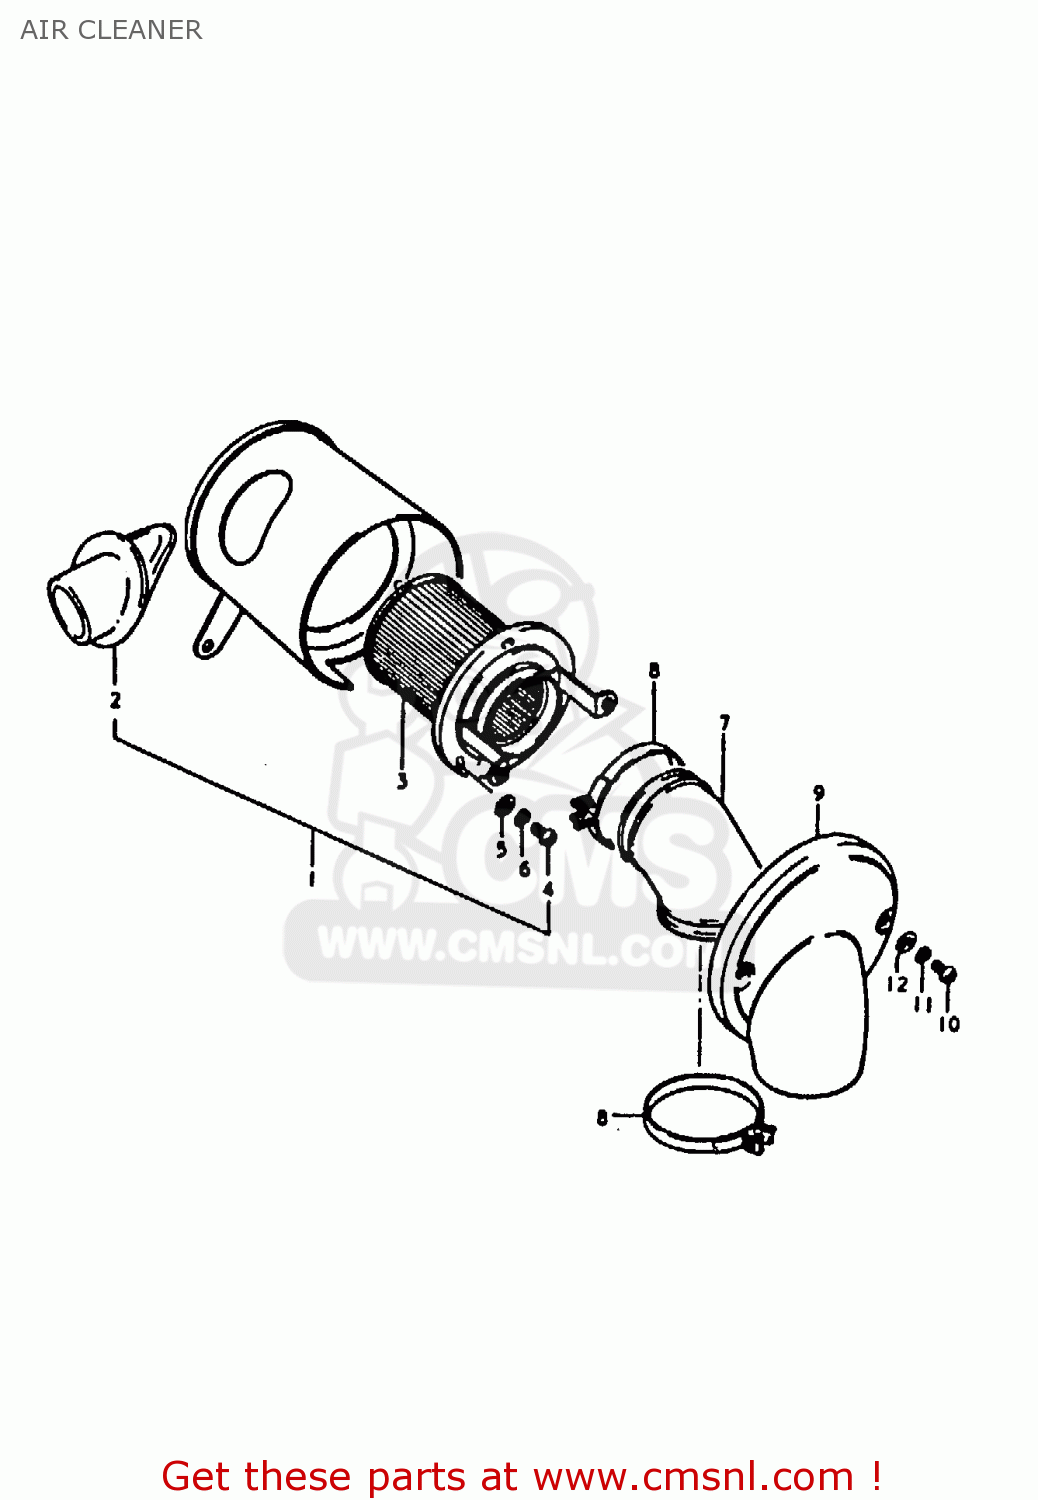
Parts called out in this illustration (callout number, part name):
1	CLEANER ASSEMBLY,AIR
2	PIPE,AIR CLEANER INLET
3	FILTER ASSY
4	SCREW
5	WASHER
6	LOCK WASHER
7	HOSE,CARBURETOR AIR INLET
8	CLAMP
9	CAP,AIR CLEANER,R
10	SCREW
11	LOCK WASHER
12	WASHER
